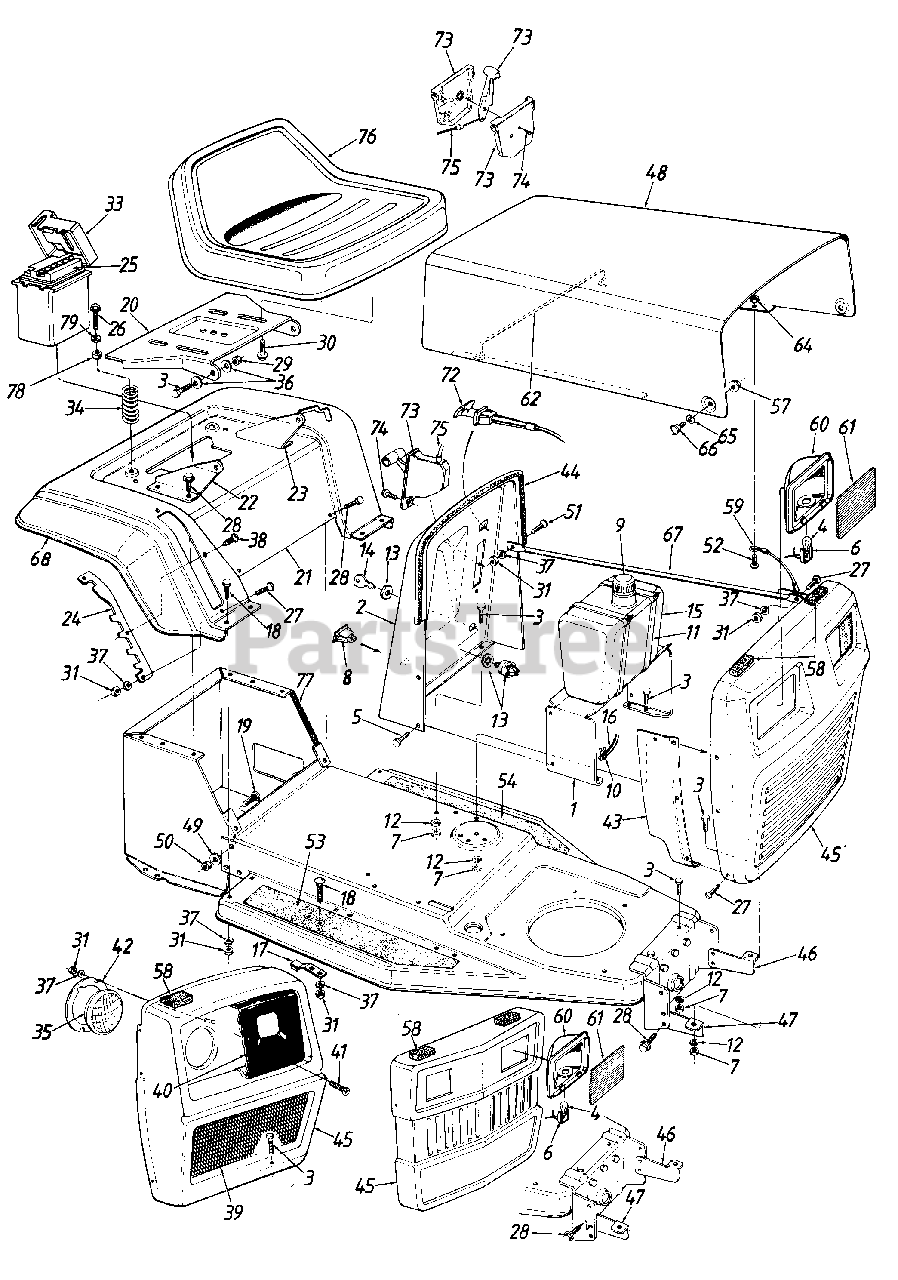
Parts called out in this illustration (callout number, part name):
1	Dash Panel Support Brkt.
4	Bulb
5	Hex AB-Tap Scr. 1/4 x .62"
6	Socket
7	Hex Nut 5/16-18 Thd.*
8	Light Switch
9	Gas Gauge
10	Hose Clamp
11	Cable Tie
12	L-Wash. 5/16" I.D.*
13	Ignition Switch
14	Ignition Key
15	Fuel Tank
16	Gas Line
17	Blade Brake Ass'y.
18	Carriage Bolt 1/4-20 x .62"
19	Ribbed Neck Bolt 3/8-24 x .8"
20	Seat Pivot Brkt.
21	Rear Fender
22	Seat Hinge Support Brkt.-R.H.
23	Seat Hinge Support Brkt.-L.H.
24	Deck Lift Index Brkt.
25	Battery
26	Hex Wash. Hd. Self-Tap Scr. 5/16-18 x 1" Lg.
27	Truss Mach. Scr. 1/4-20 x .75" Lg.
28	Hex AB-Tap Scr. 5/16 x .75" Lg.
29	Hex L-Nut 5/16-18 Thd.
30	Hex Self-Tap Scr. 3/8-16 x .75" Lg.
31	Hex Nut 1/4-20 Thd.*
33	Battery Box w/Cover
34	Compression Spring
35	Headlight
36	Bell-Wash. 5/16" I.D.
37	L-Wash. 1/4" I.D.*
38	Hex Wash. Hd. Self-Tap Scr. #10 x .5" Lg.
39	Grille Insert
40	Bezel
41	C-Sunk Mach. Scr. 1/4-20 x 1.5"
42	Headlight Retainer
43	Side Panel-R.H.
44	Trim Strip 261/2" Lg.
46	Grille Mtg. Brkt.-L.H.
47	Grille Mtg. Brkt.-R.H.
50	Hex L-Nut 3/8-24 Thd.
51	Hex Bolt 1/4-20 x .62" Lg.
52	Truss Mach. Scr. #10-24 x .5" Lg.
53	Foot Pad-R.H.
54	Foot Pad-L.H.
57	Lock Nut 1/4-28 Thd.
58	Foam Strip
59	Hood Stop
60	Headlight Housing
61	Lens
62	Hood Spring
64	Hex Sems Nut #10-24 Thd.
65	Spr. Wash. .39" I.D. x .62" O.D.
66	Shld. Bolt
67	Grille Support
68	Trim Strip 79" Lg.
72	Choke Control
73	Throttle Control Box
74	Truss AB-Tap Scr. #10 x .5"
75	Throttle Wire
76	Seat Assembly
77	Trim Strip 5" Lg.
78	Rubber Washer
79	Fl-Wash. .344" I.D. x .88" O.D.
